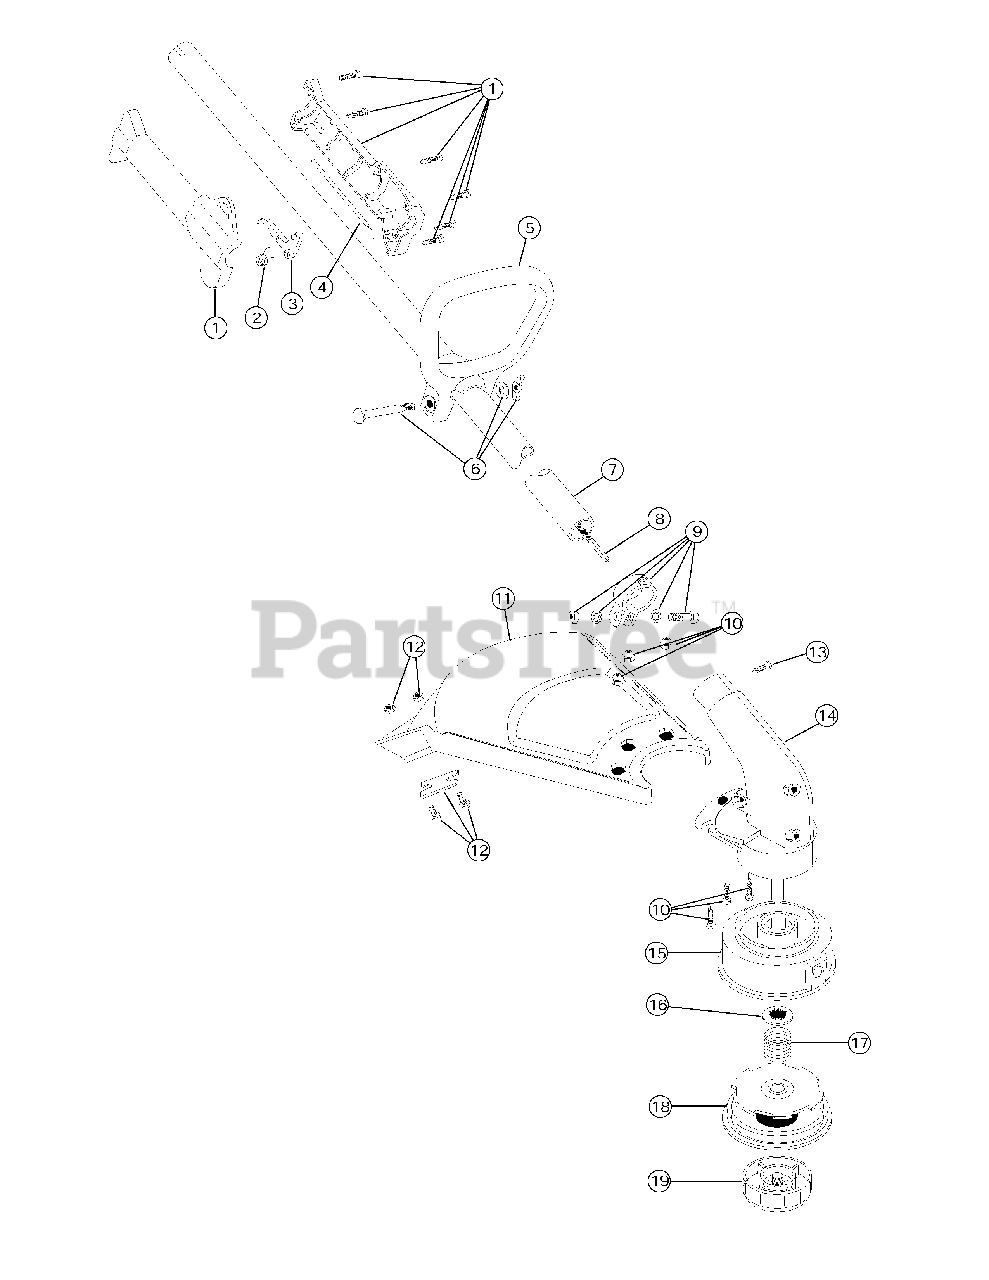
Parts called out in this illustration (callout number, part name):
1	Throttle Housing Assembly (includes 2 & 3)
2	Throttle Trigger Spring
3	Throttle Trigger
4	Throttle Cable
5	D-Handle Assembly (includes 6)
6	D-Handle Hardware
7	Drive Shaft Housing Assembly (includes 8)
8	Flexible Drive Shaft
9	Lower Clamp Assembly (includes 13)
10	Guard Mounting Hardware
11	Guard Assembly (includes 12)
12	Blade Assembly
13	Anti-Rotation Screw
14	Gearbox Assembly (includes 15 & 16)
15	Outer Spool Assembly (includes 16)
16	Retainer
18	Inner Reel
19	Bump Head Knob Assembly
